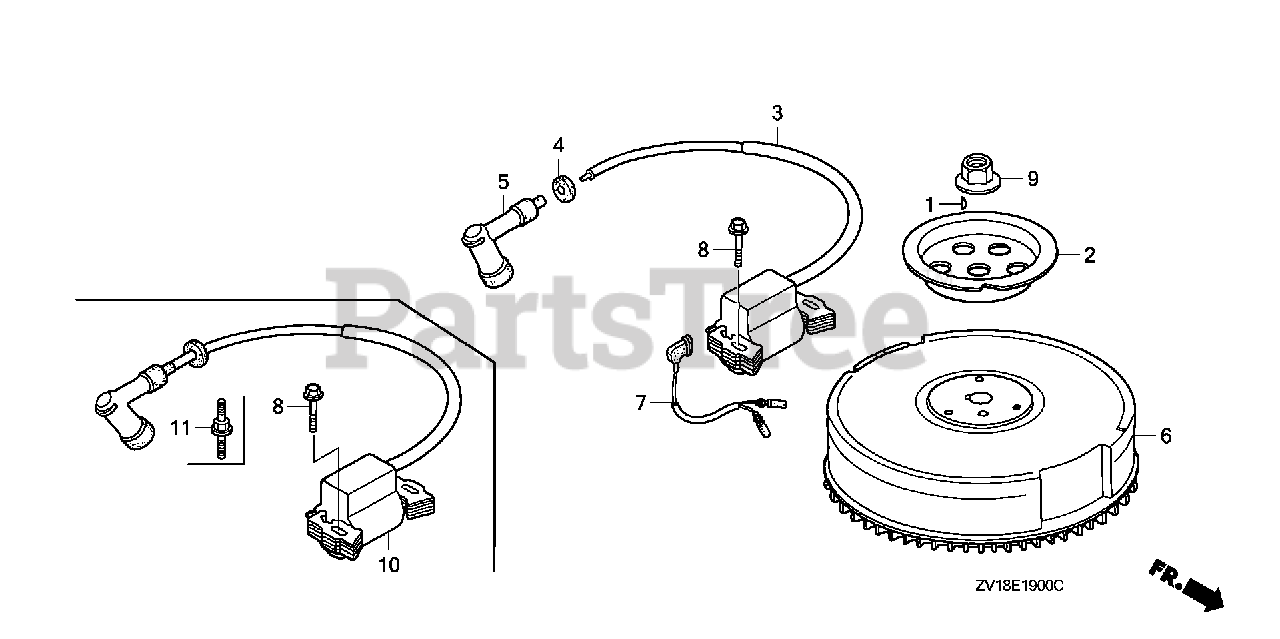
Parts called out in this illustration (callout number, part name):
1	KEY, SPECIAL WOODRUFF (25X18)
2	PULLEY, STARTER
6	FLYWHEEL *TBLACK* (BLACK)
7	WIRE, STOP SWITCH
8	BOLT, FLANGE (6X28) (CT200)
9	NUT, SPECIAL (14MM)
10	COIL ASSY., IGNITION
11	BOLT, SPECIAL (6MM)
